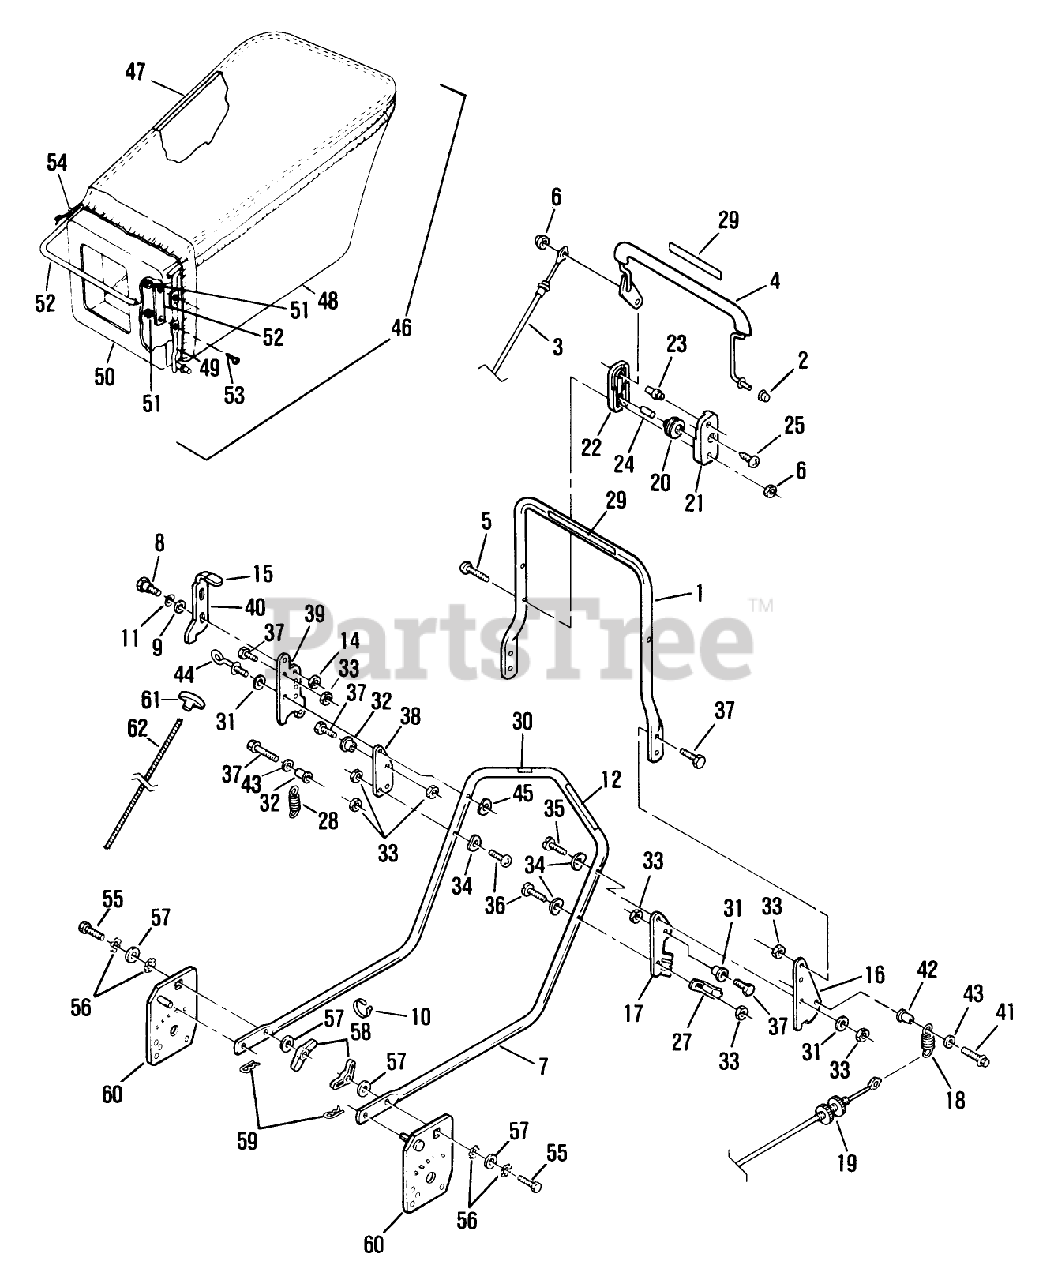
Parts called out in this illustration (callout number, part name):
6	NUT C/LOCK E
8	BOLT RB&W
9	WASHER M
14	LOCKNUT E
18	SPRING
19	CABLE AY
23	COLUMN
24	PIN SKF
25	SCREW
33	NUT-LOCK F
34	WASHER-CURVED
35	SCREW LARSON
42	SPACER ROCKFORD
43	WASHER
47	HANGER BAG TROX
50	BAG ADAPTOR PL
51	LOCKNUT E
56	LOCK WASHER LARSON
57	WASHER
58	NUT-WING
61	HANDLE START UM&D
